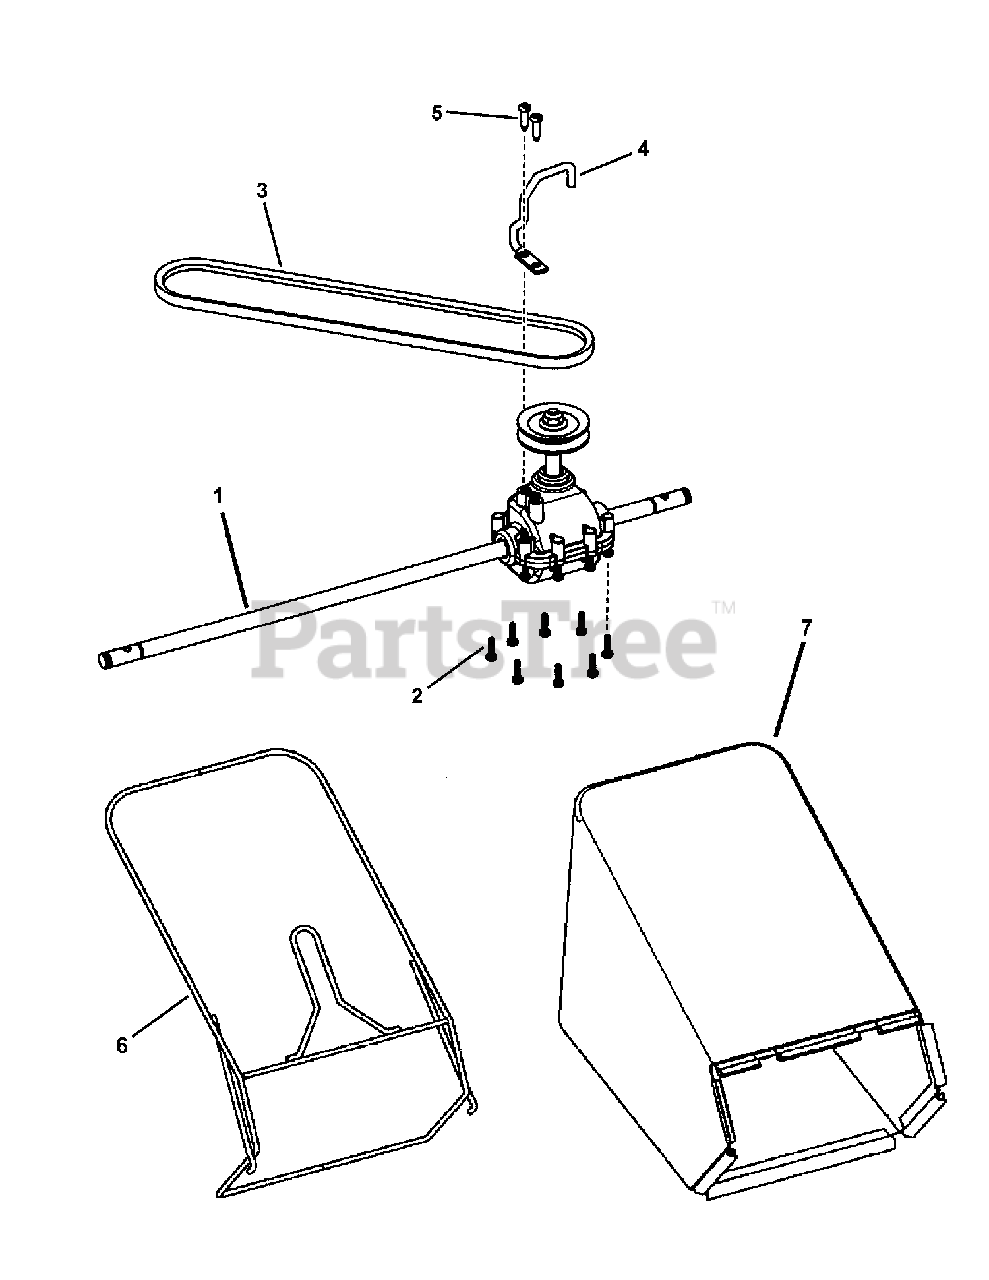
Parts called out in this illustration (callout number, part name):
1	TRANSMISSION, Rocker, 22" WBM, VS
2	SCREW, 7mm x 1 x .550 AB Point
3	BELT, 3L, 31.94" Effective Length
4	BELT GUIDE, Transmission, 22" WBM
5	SCREW, Pan Head Cross Recess, Tapping
6	BAG FRAME, 22" WBM
7	GRASS BAG, 22" Rear Discharge
